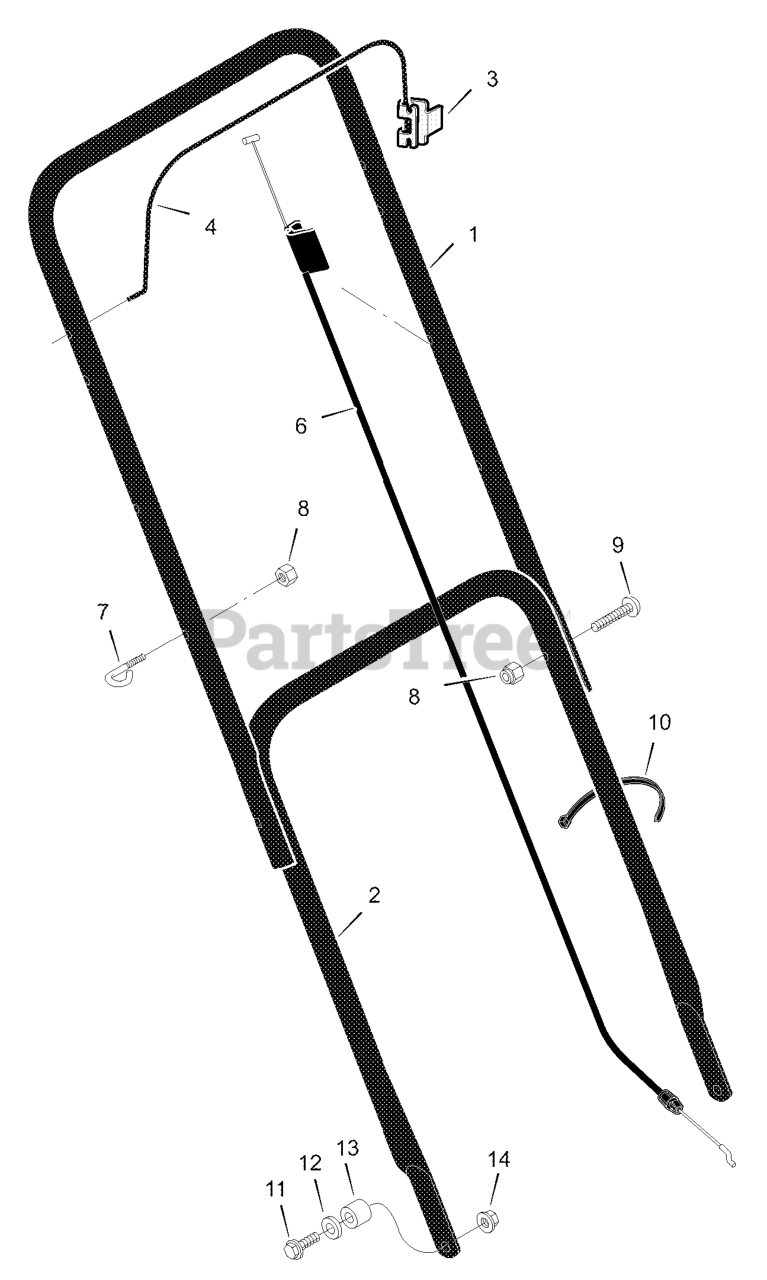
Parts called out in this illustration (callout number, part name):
1	Handle, Upper
2	Handle, Lower
3	Bracket, Stop Lever
4	Lever, Stop
6	Engine Stop Cable
7	GUIDE, ROPE
8	Locknut
10	Fastener, Cable
12	Washer
